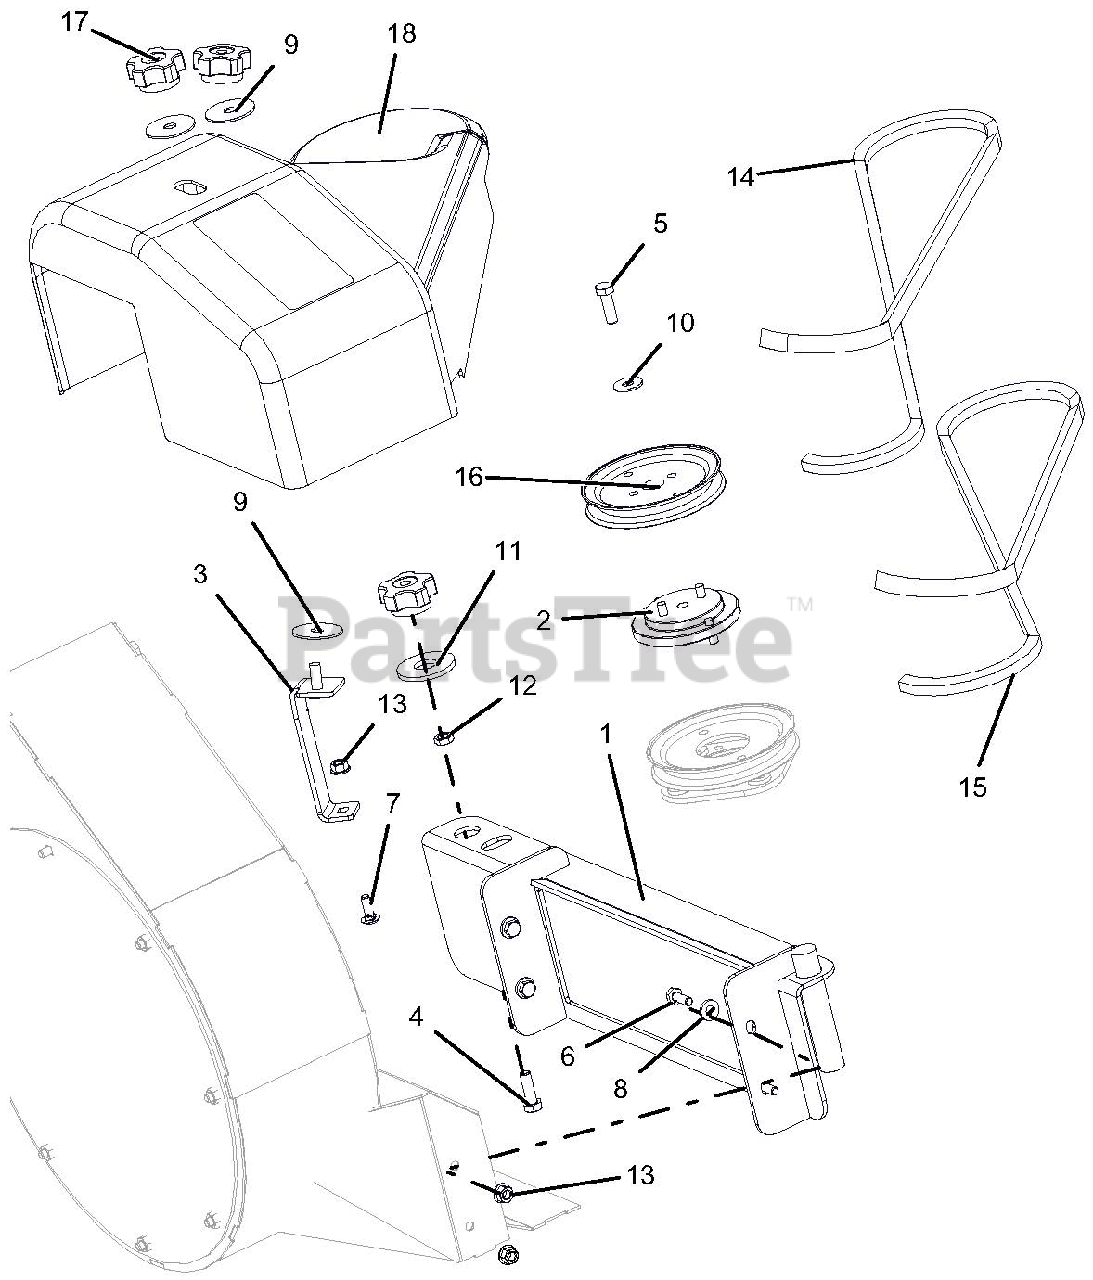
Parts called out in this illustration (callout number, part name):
1	WLDMT, PUMP MOUNT
2	ASM, BLOWER SHEAVE ADAPTER
3	WLDMT, BAGGER BELT COVER BRKT
4	BLT-HEX .31-18X1.00 GR8 YWZC
5	BLT-HEX .31-18X1.00 GR8 EP30 YWZC
6	BLT-HEX .25-20X.75 GR5 YWZC
7	BLT-RDHDSQNK .25-20X.75 G5 YWZC
8	WSHR-FL-STL.281X.62X.065 YWZC
9	WSHR-FL-STL .380X1.50X.062 YWZ
10	WSHR-FL-STL .34 X 1.125 X .135 YWZ
11	WSHR-FL-STL.688X1.75X.134 YWZ
12	NUT, JAM .312-18 YWZC
13	NUT, LK-TOP-FLG .25-20 YWZC
14	BELT, BAGGER 52"
15	V-BELT, 42"
16	PULLEY, V-4.25 OD X .68 ID YWZC
17	KNOB, CLAMPING
18	COVER, BAGGER BELT-W/DECAL
